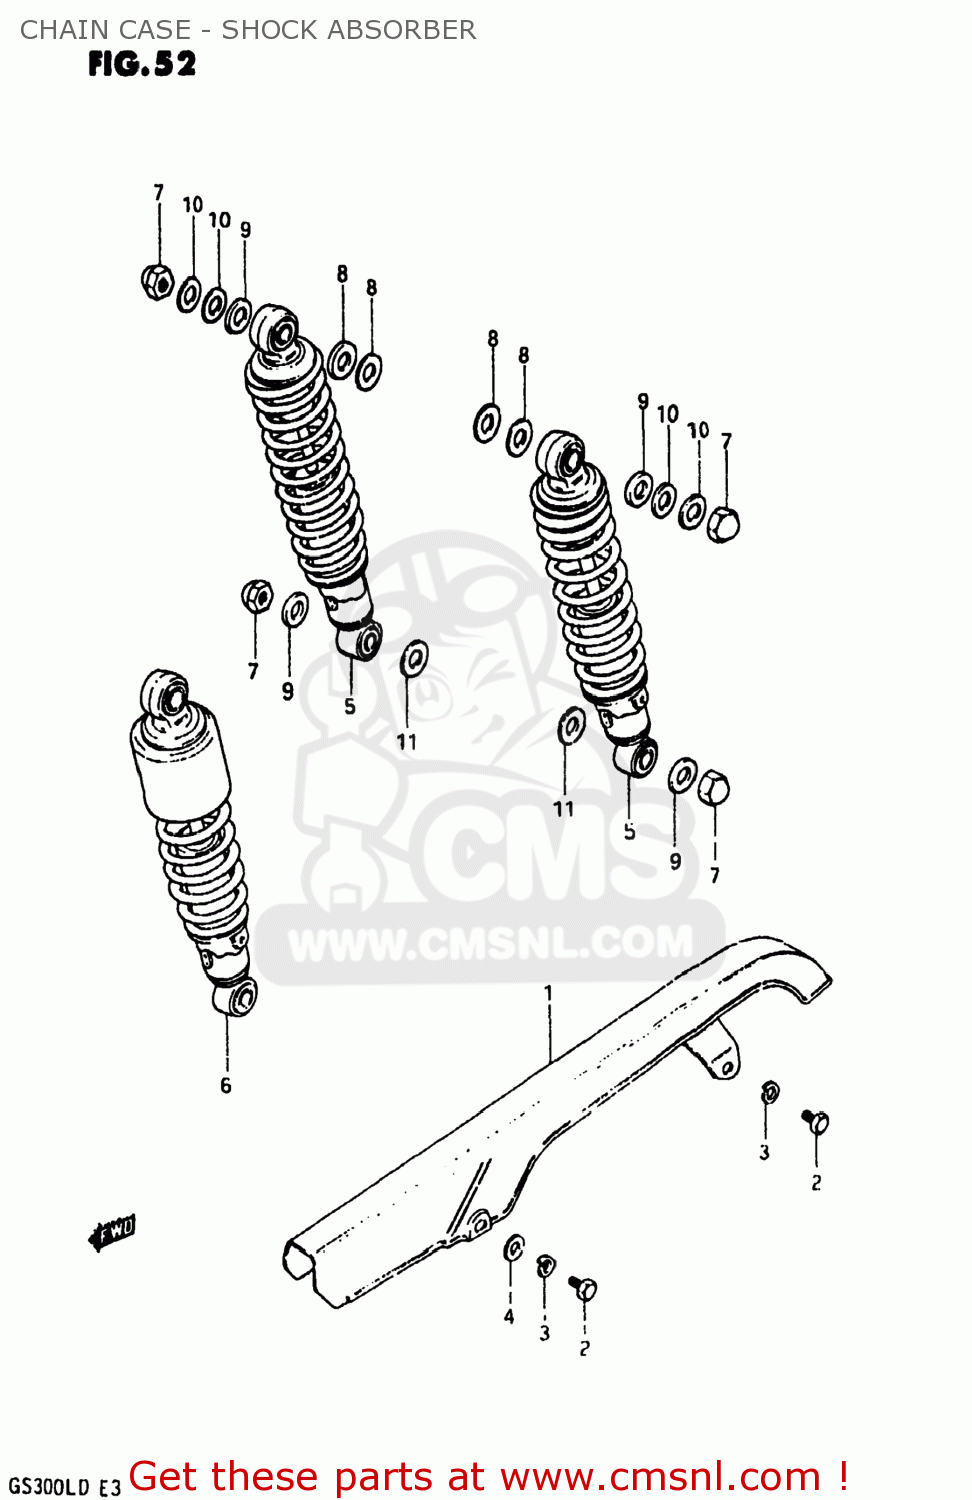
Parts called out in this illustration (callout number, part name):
1	CASE,CHAIN
2	BOLT
3	LOCK WASHER
4	WASHER
5	ABSORBER ASSEMBLY,REAR SHOCK
6	ABSORBER ASSEMBLY,REAR SHOCK
7	NUT, LOWER LH
8	WASHER
9	WASHER
10	WASHER(10.5X24X3.2)
11	WASHER (12.5X24X1.6)
